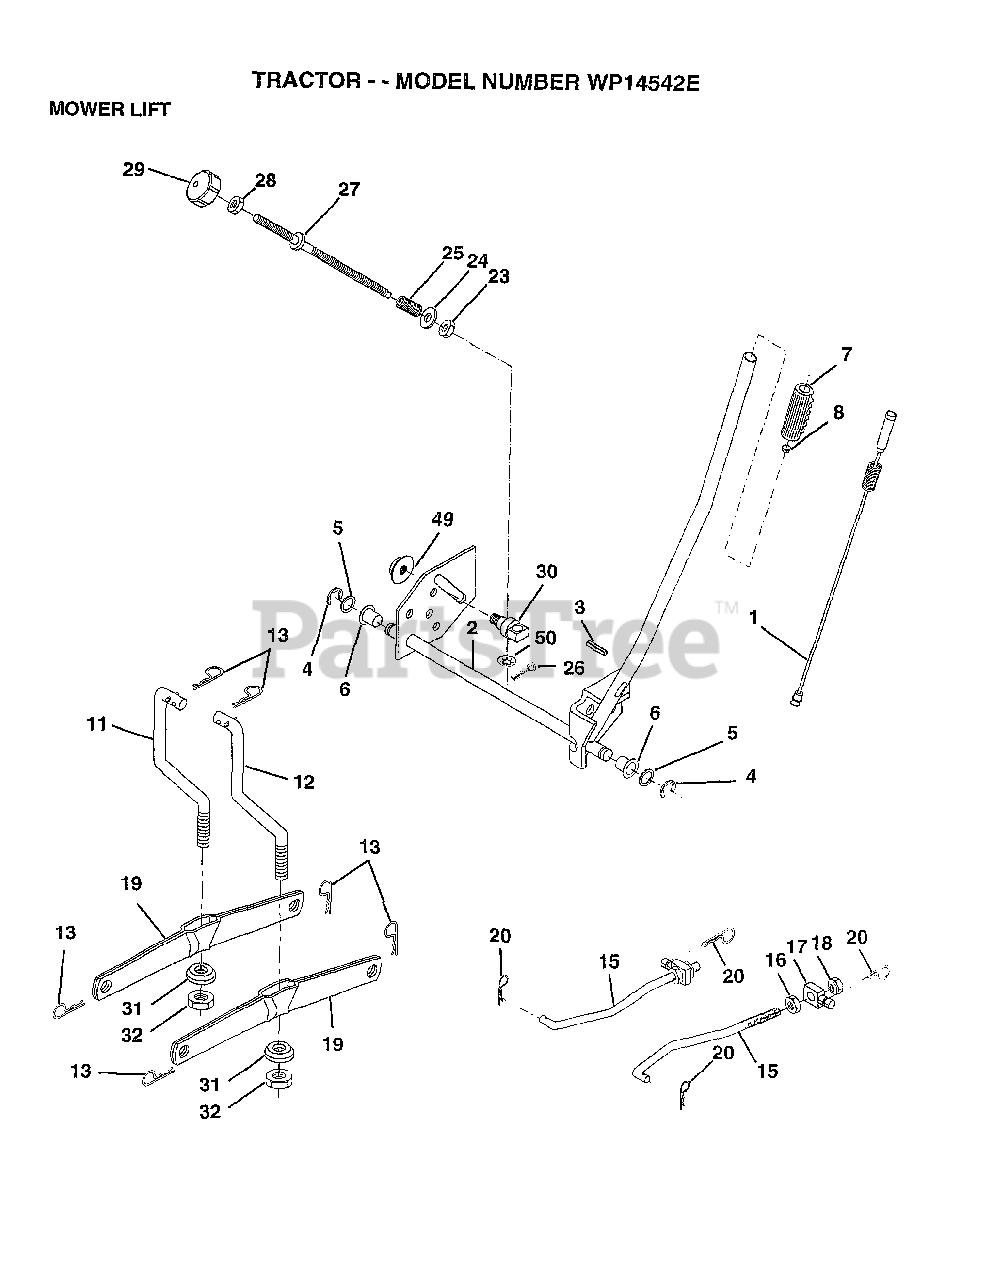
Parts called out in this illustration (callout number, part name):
1	WIRE.ASM.INNER.SP
2	"SHAFT AMS LIFT,RH"
3	PIN GROOVE
5	WASHER
6	NYLON BEARING
7	GRIP
15	LINK.FRONT
16	NUT
17	TRUNION
18	NUT LTV
19	ARM SUSP REAR
20	RETAINER SPRING
23	NUT T
24	WASHER
25	SPRING.COMP.INF.H
27	ROD.ADJ.LIFT
28	NUT
29	KNOB INF 3/8-16
30	TRUNNION
31	BEARING PVT LH
32	NUT.CROWNLOCK.3/8
49	NUT.HXFLG.LOCK.
